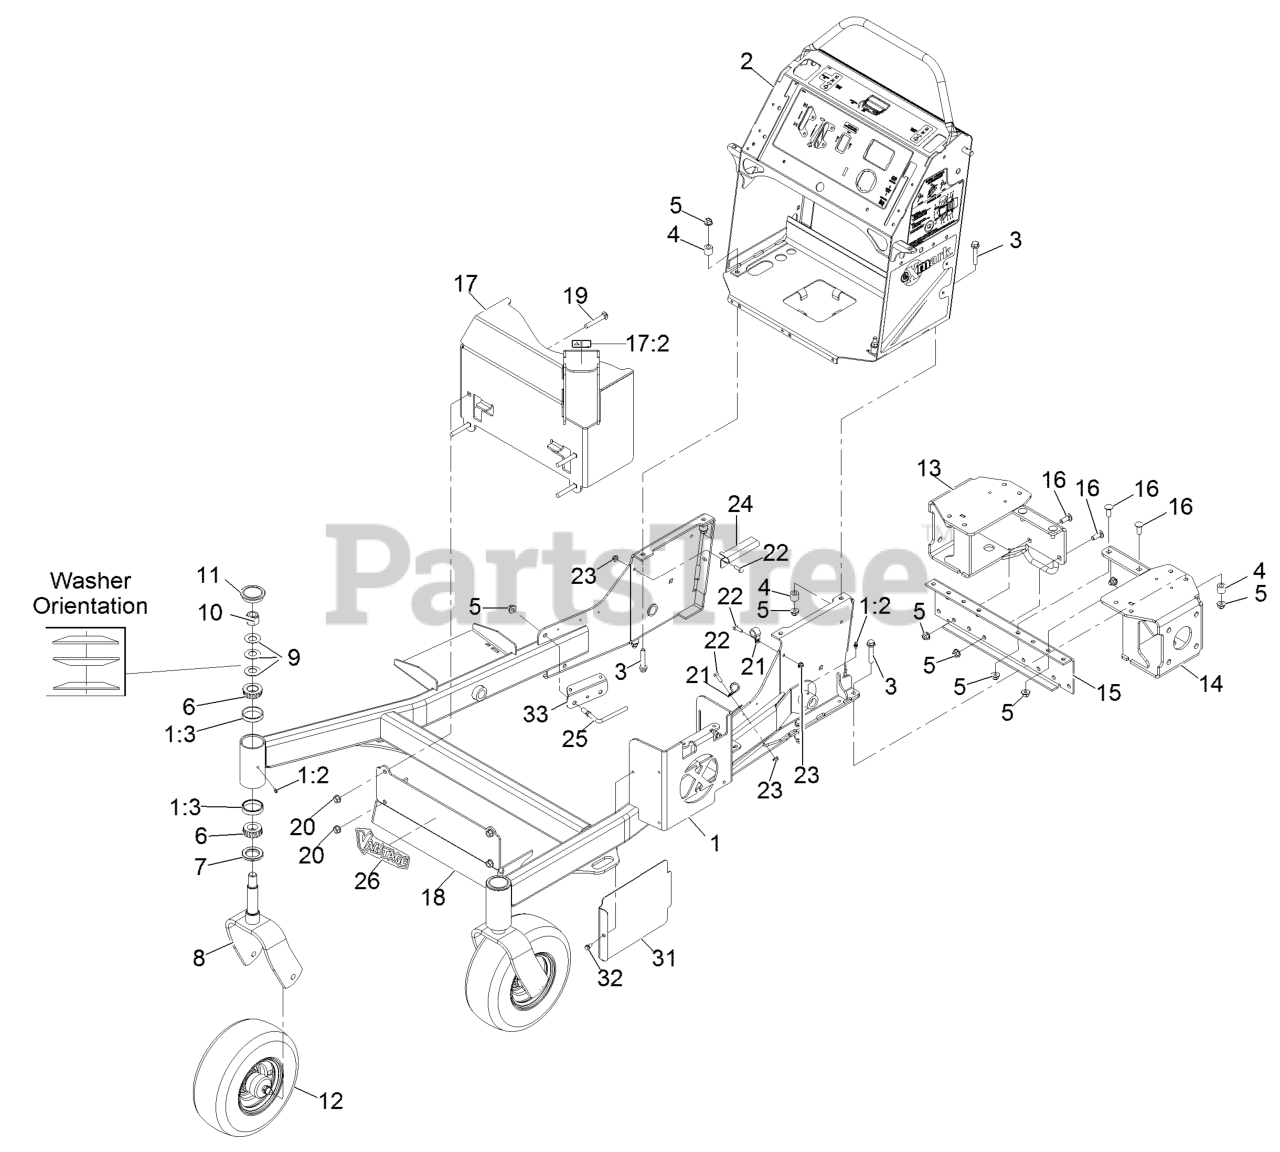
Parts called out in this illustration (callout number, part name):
1	FRONT FRAME ASM
1:2	FITTING-GREASE
2	CONTROL TOWER ASM
3	SCREW-HHF
5	NUT-HF, NI
6	Cone-Bearing Tapered Roller
7	SEAL-GREASE
8	FORK-CASTER
9	WASHER-BELLVILLE
10	NUT-LOCK, NI
11	CAP-GREASE
12	WHEEL/TIRE AND BEARING AS
13	RH MOTOR MOUNT ASM
14	LH MOTOR MOUNT ASM
15	MOUNT-MOTOR, CENTER
16	SCREW-CARR
17	MUFFLER GUARD ASM
17:2	DECAL-WARNING
18	PANEL-GUARD
19	SCREW-CARR
21	CLAMP-CABLE
22	SCREW-HH
24	BRACKET-HOSE, FUEL (DOUBL
25	GUIDE-HOSE, SUPPORT
26	DECAL-VANTAGE LOGO
31	SHIELD-HEAT, TALL
32	SCREW-HWH
33	GUARD-HOSE
